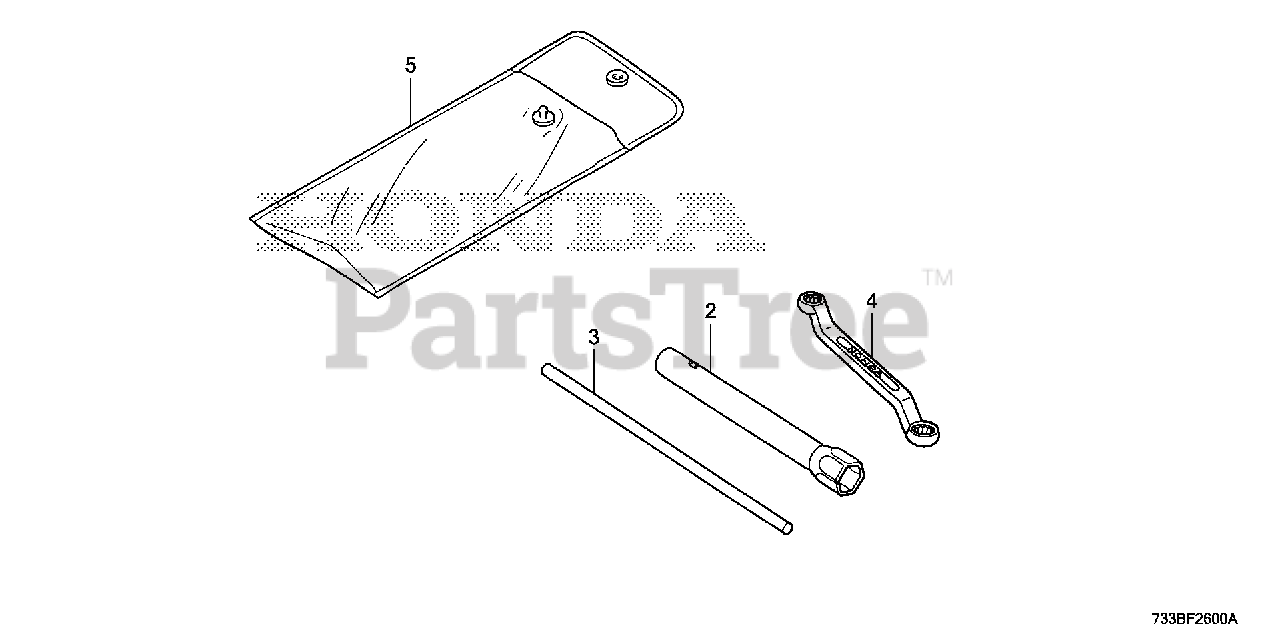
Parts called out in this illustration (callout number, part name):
2	WRENCH, SPARK PLUG
3	HANDLE, BOX WRENCH
4	WRENCH, EYE (10X12)
5	BAG, TOOL (230MM)
